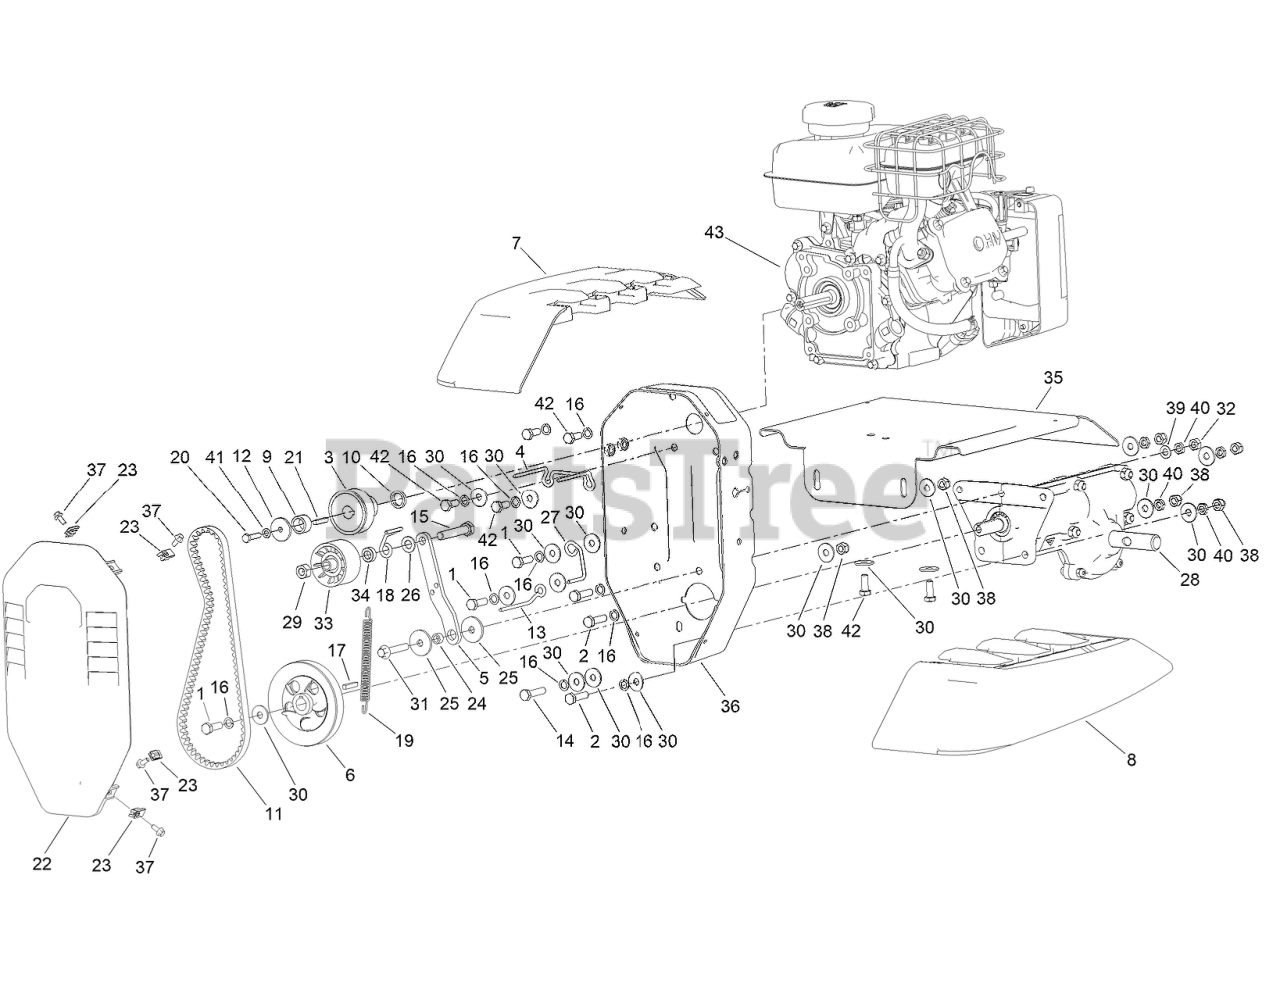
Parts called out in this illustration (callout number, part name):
1	SCREW-HHCS
2	SCREW-HHCS
3	PULLEY-16MM
4	BELT GUIDE-DOUBLE
6	PULLEY-TRANSMISSION
7	SHIELD-LEFT
8	SHIELD-RIGHT
9	BUSHING
10	BUSHING
12	WASHER-FLAT
13	BELT GUIDE-SINGLE
14	SCREW-HHCS
15	SCREW-HHCS
16	WASHER-LOCK
17	KEY-SQUARE
18	BELT CATCH
19	TENSION SPRING
20	SCREW-HHCS
21	KEY-SQUARE
22	COVER-PULLEY
23	CAGE NUT
24	BUSHING
25	WASHER-WIDE
26	WASHER-PLAIN
27	GUIDE-BELT
28	MOUNT-TRANSMISSION
29	NUT-HEX
30	WASHER-FLAT
31	SCREW-HHF
32	NUT-HEX
33	PULLEY-IDLER
34	SPACER-18MM
35	SHIELD-CENTER
36	BOX-PULLEY
37	SCREW-HHF
38	NUT-HEX
39	WASHER-FLAT
41	WASHER-LOCK
42	SCREW-HHCS
43	ENGINE-TORO [99CC]
